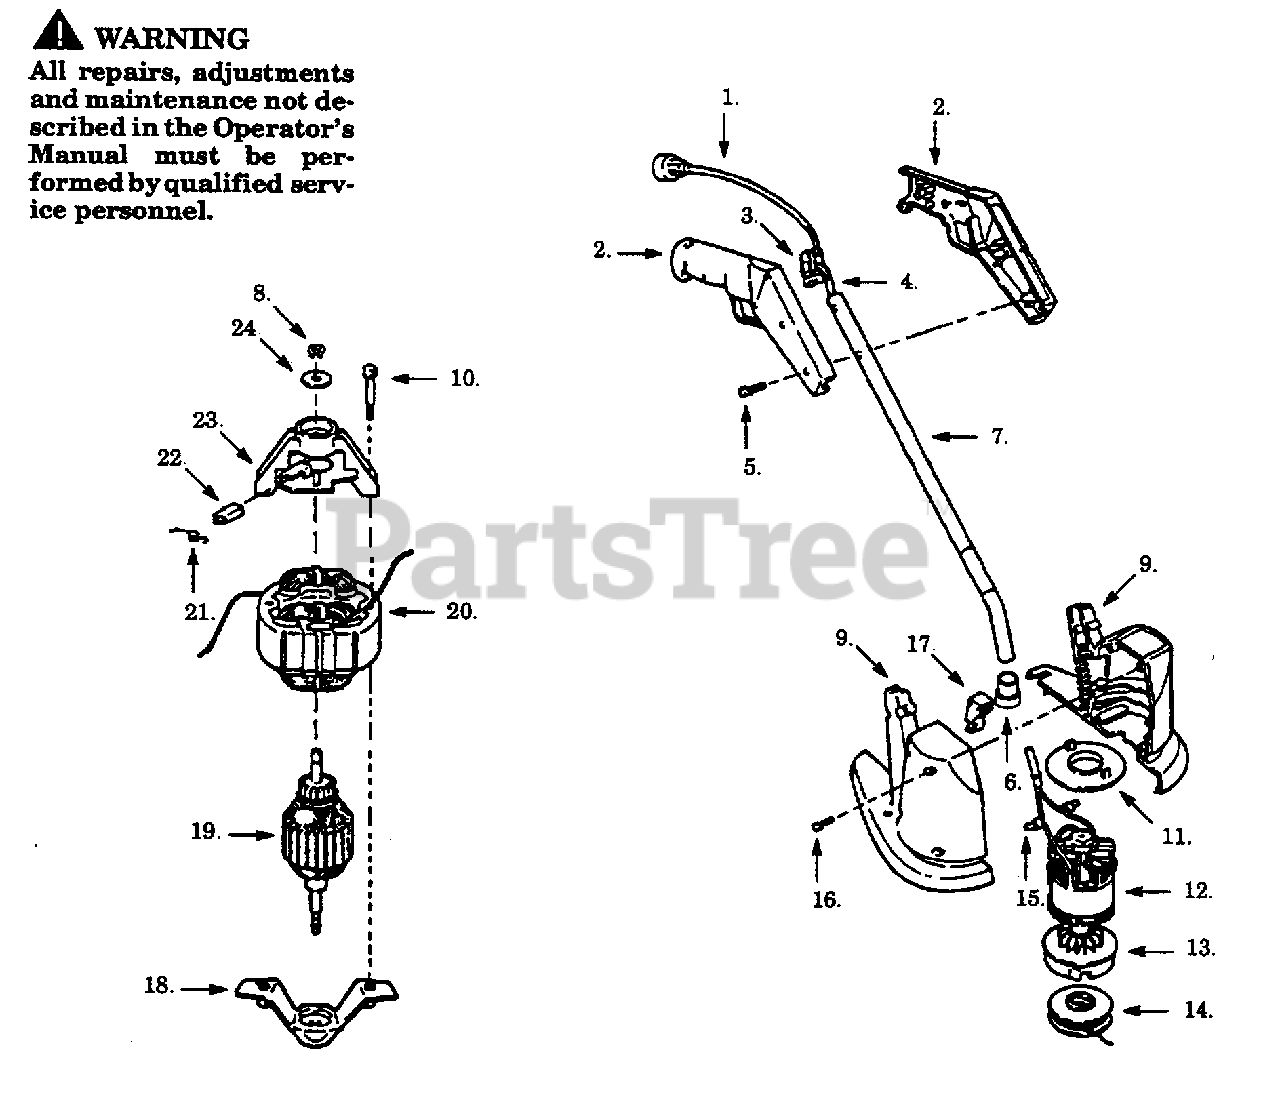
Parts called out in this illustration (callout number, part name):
1	Power Cord
2	Handle Set
3	Trigger Switch
6	Rain Guard
8	Retaining Ring
9	Housing Set
11	Air Baffle
12	Motor Ass'y.
13	Rotating Head
14	Spool & Line
15	Terminal Cap
17	Blade Retainer Ass'y.
18	Endbell Ass'y. (Drive)
19	Armature Ass'y.
20	Field Ass'y.
21	Brush Spring
22	Carbon Brush
23	Bracket/Plate Ass'y.
